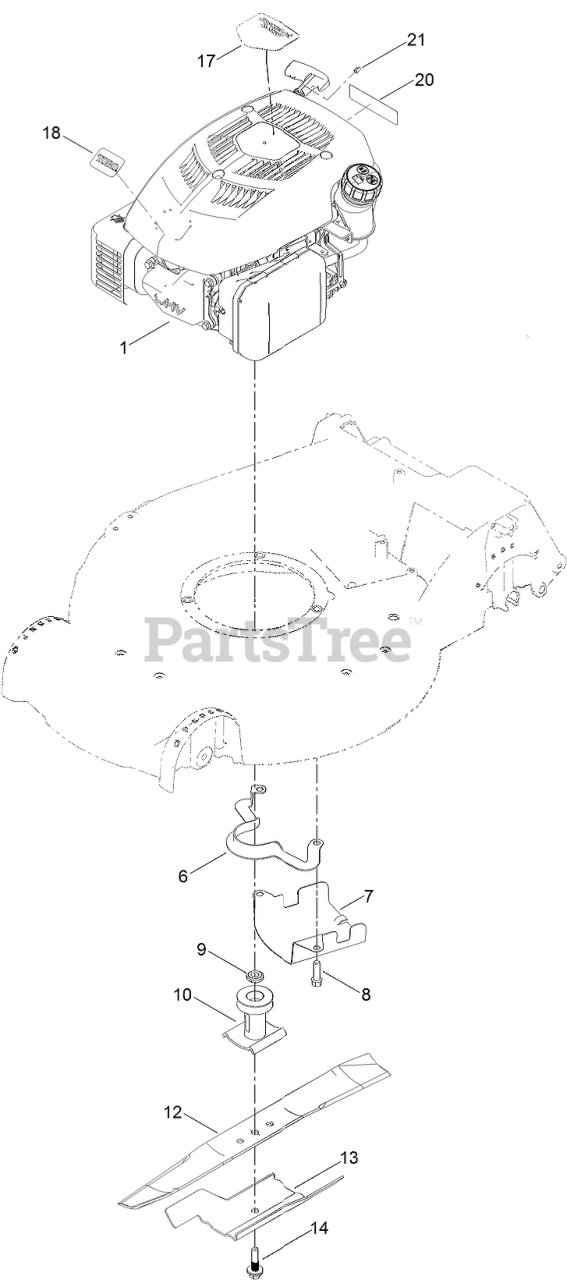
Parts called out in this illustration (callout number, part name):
1	ENGINE-1P65F-2
6	GUIDE-BELT
7	SHIELD-GRASS
8	SCREW-TAPTITE
9	SPACER-DRIVER
10	DRIVER-BLADE
12	BLADE-21IN, RECYCLING
13	ACCELERATOR-BLADE
14	BOLT-BLADE
17	DECAL-SHROUD
20	DECAL-ARRESTOR, SPARK
21	STOP-ROPE
